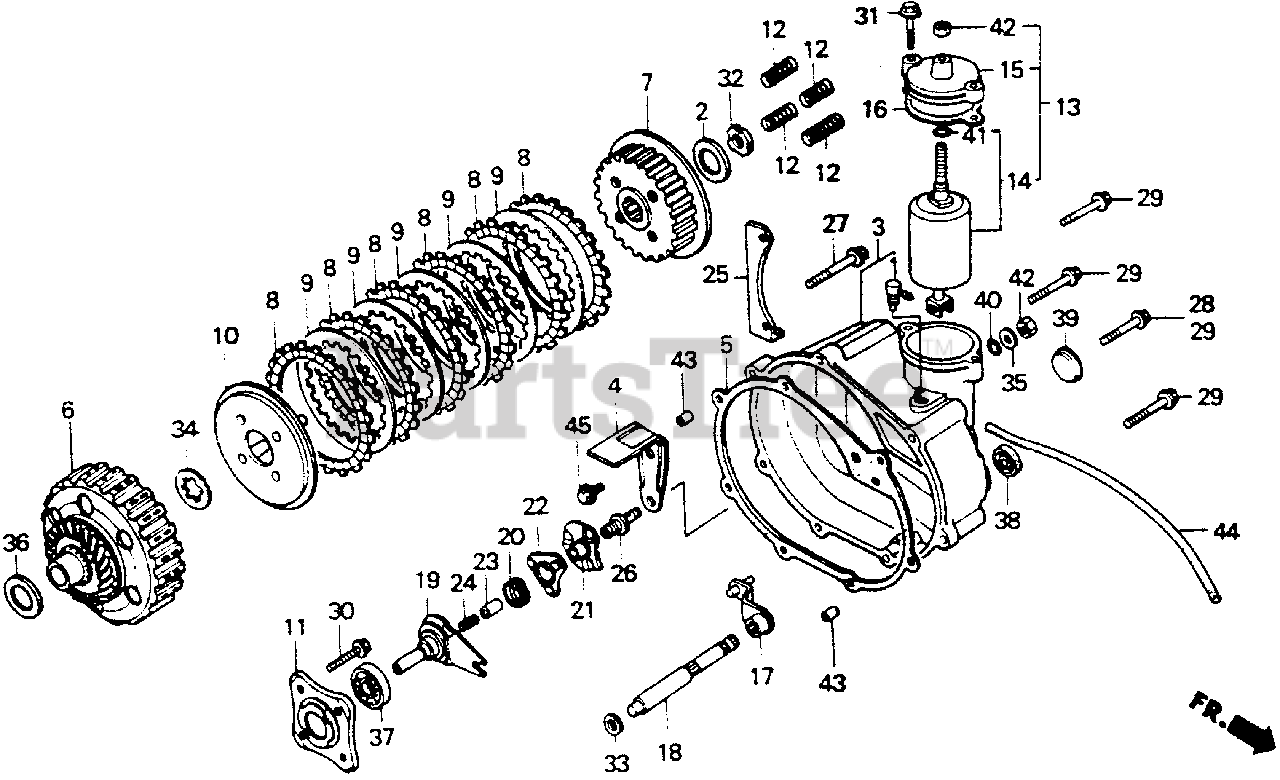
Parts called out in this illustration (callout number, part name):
1	JOINT, BREATHER
2	WASHER, OIL FILTER ROTOR LOCKING
3	COVER, CLUTCH
4	GUIDE, OIL
5	GASKET, CLUTCH COVER
6	CLUTCH (OUTER)
7	CENTER, CLUTCH (NOT AVAILABLE)
8	DISK, CLUTCH FRICTION
9	PLATE, CLUTCH
10	PLATE, CLUTCH PRESSURE
11	PLATE, CLUTCH LIFTER
12	SPRING, CLUTCH
13	DAMPER SET, CLUTCH (N/A: SEE COMPONENTS)
14	DAMPER ASSY., CLUTCH
15	BRACKET, DAMPER (UPPER)
16	GASKET, CLUTCH DAMPER
17	LEVER, CLUTCH
18	SHAFT, CLUTCH
19	PLATE, CLUTCH CAM (NOT AVAILABLE)
20	SPRING, CAM PLATE SIDE
21	PLATE, CLUTCH LIFTER
22	RETAINER, CLUTCH BALL
23	THROUGH, OIL
24	SPRING, OIL THROUGH
26	BOLT, CLUTCH ADJUSTING
27	BOLT, FLANGE (6X40)
28	BOLT, FLANGE (6X35) (CT200)
29	BOLT, FLANGE (6X32)
30	BOLT, SPECIAL FLANGE (6X28)
31	BOLT, FLANGE (6X25) (CT200)
32	NUT, LOCK (16MM)
33	WASHER, THRUST (10MM)
34	WASHER, SPLINE (20MM)
35	WASHER (8MM)
36	SHIM, MAINSHAFT (20.2X30X1.25)
36	SHIM, MAINSHAFT (20.2X30X1.30)
36	SHIM, MAINSHAFT (20.2X30X1.35)
36	SHIM, MAINSHAFT (20.2X30X1.40)
36	SHIM, MAINSHAFT (20.2X30X1.45)
36	SHIM, MAINSHAFT (20.2X30X1.50)
36	SHIM, MAINSHAFT (20.2X30X1.55)
36	SHIM, MAINSHAFT (20.2X30X1.60)
36	SHIM, MAINSHAFT (20.2X30X1.65)
36	SHIM, MAINSHAFT (20.2X30X1.70)
36	SHIM, MAINSHAFT (20.2X30X1.75)
37	BEARING, RADIAL BALL (16003)
38	OIL SEAL (10X20X5)
39	SEAL, PLUG (25X7)
40	O-RING (8X1.7) (ARAI)
41	O-RING (6.8X1.9)
42	NUT, HEX. (8MM)
43	PIN, DOWEL (8X14)
44	BULK HOSE, VACUUM (5X3000) (5X200)
45	BOLT, FLANGE (6X12)
